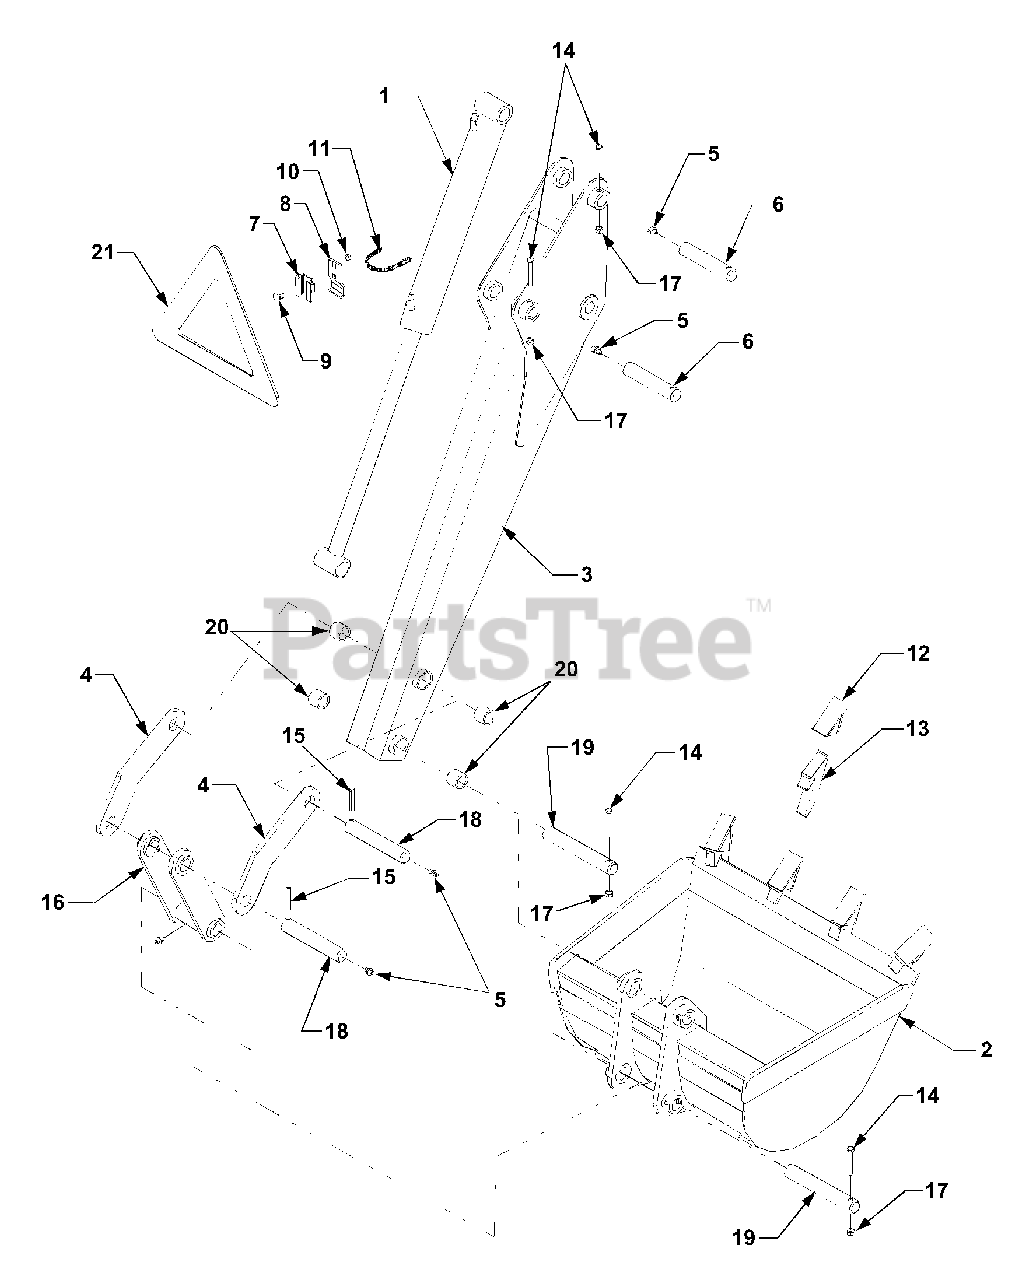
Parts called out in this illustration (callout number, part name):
1	Cylinder Ass'y. - Bucket
3	Dipperstick Ass'y.
5	Grease Nipple
8	Socket Bracket
9	Screw, M8 x 20
14	Hex Head Screw, M10 x 50
17	Hex Nut, M10 Lock
21	Reflective SMV Plate
